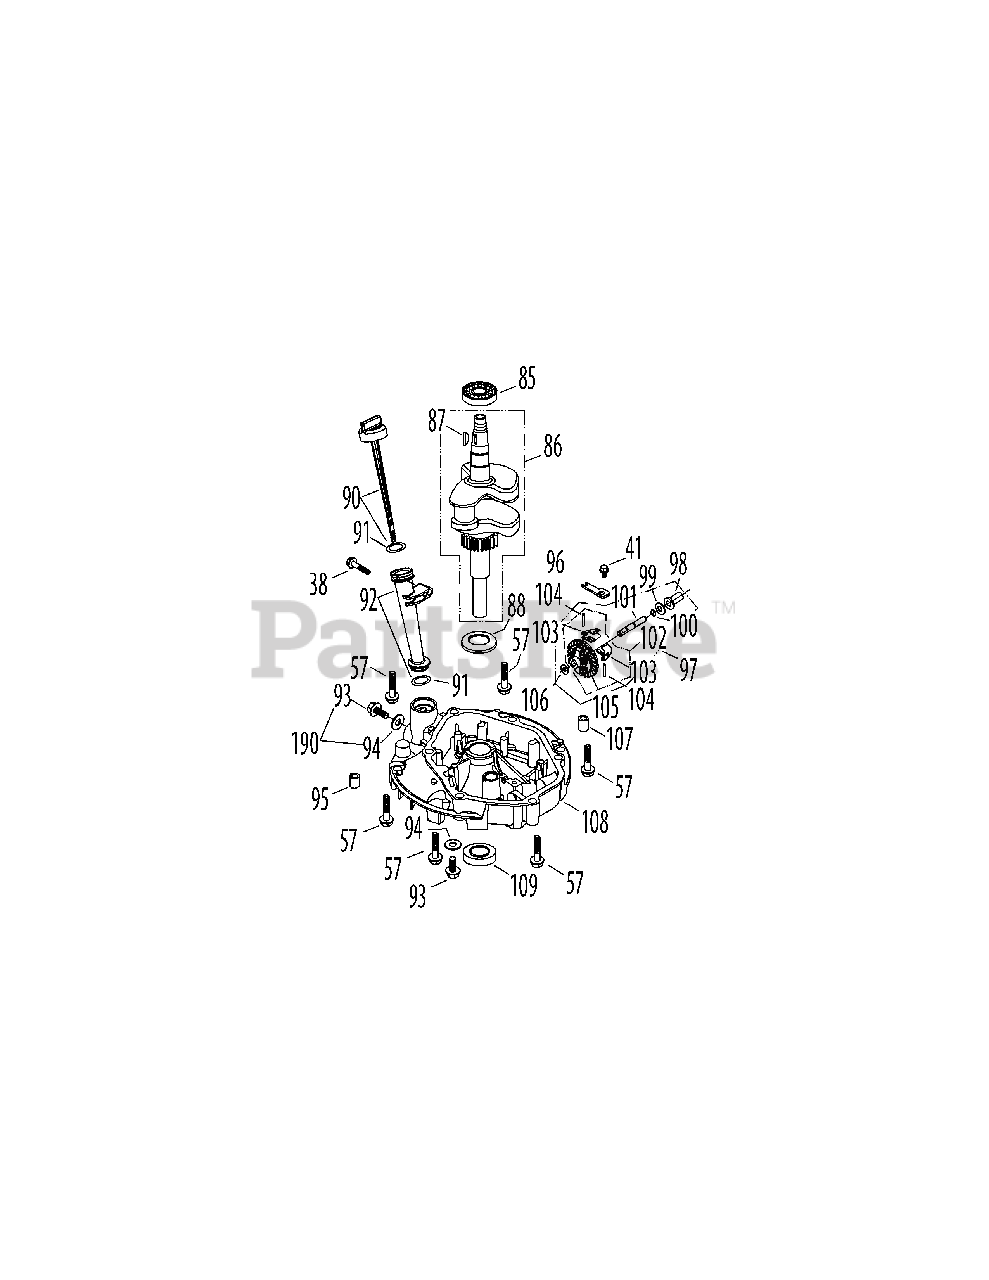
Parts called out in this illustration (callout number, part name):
38	Bolt M6×35
41	Bolt M6×14
57	Tank/Sump Bolt M8x50
85	Main Bearing
86	Crankshaft Assembly
87	Woodruff Key
88	Crankshaft Thrust Washer
90	Dipstick Assembly
91	Dipstick / Oil Fill Tube O-Ring
92	Oil Filler Tube Assemlby
93	Oil Drain Plug
94	Oil Drain Plug Washer
95	Crankcase Cover Dowel 9×14
96	Governor Gear Mounting Plate
97	Governor Gear/Shaft Assembly
107	Crankcase Cover Dowel 7×14
108	Crankcase Cover - dual drain
109	Lower Crankshaft Seal
190	Oil Drain Plug and Washer Ass'y
